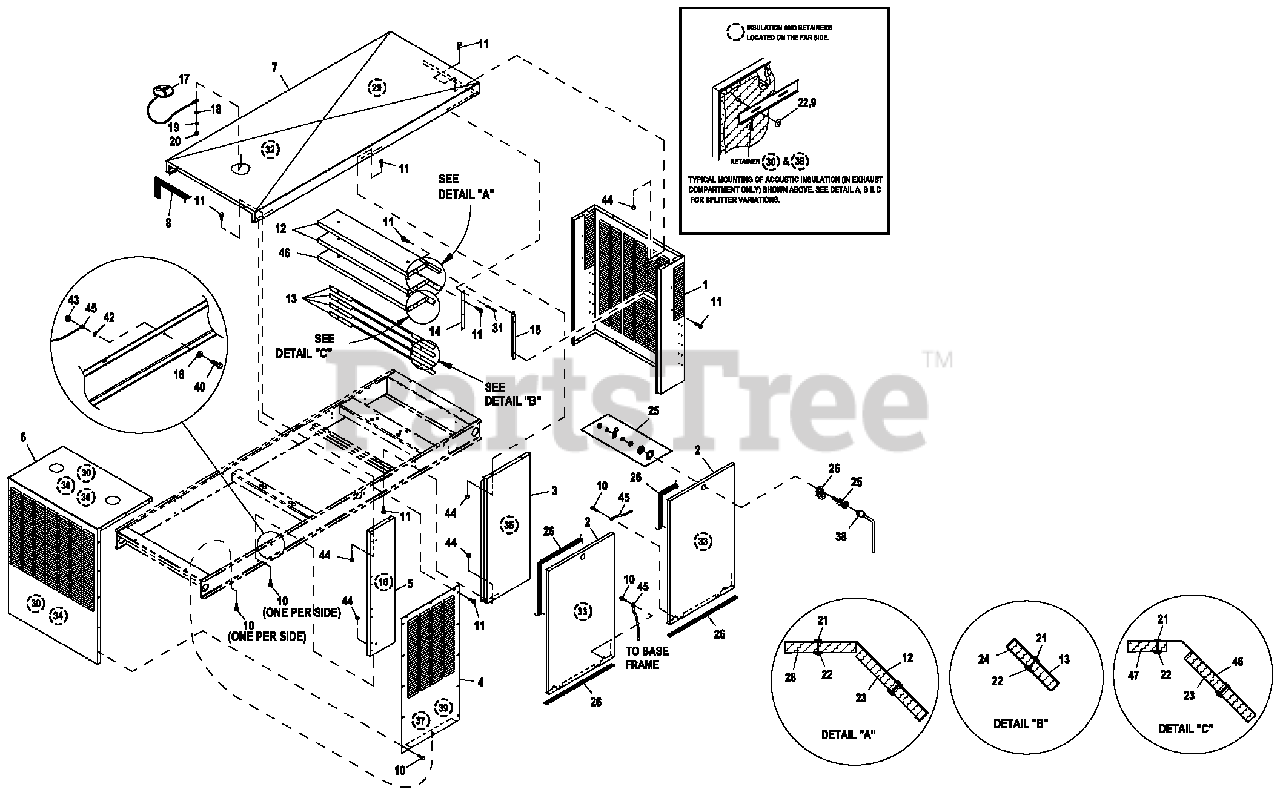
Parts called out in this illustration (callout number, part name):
1	REAR WRAP C5
2	DOOR C5
3	CENTER SUPPORT C5
4	DISCHARGE DUCT LH & RH SIDE C5
5	FRONT CORNERS C5
6	DUCT CENTER DISCHARGE RAW
7	ROOF C5ALUM
8	STRIP SEALANT 1/8X1 (44.5"LG)
9	WASHER SELF LOC KING DOME #8-32
10	SCREW TH-FRM M6 W/CAP SH KPRF W
11	SCREW THF M6-1 X 16 N WA Z/JS
12	SPLITTER
13	SPLITTER SHORT
14	STRINGER SPLITTER C3
15	SUPPORT SPLITTER C5 130 KW
16	INSUL CORNER POST
17	ASSY ACCESS COVER
18	WASHER FLAT 1/4-M6 ZINC
19	WASHER LOCK M6-1/4
20	NUT HEX 1/4-20 STEEL
21	INSULATION RETAINMENT HANGER
22	WASHER SELF LOC KING DOME #4-40
23	INSUL SPLITTER
24	INSUL SHORT LOUVER
25	VISE-ACTION LATCH SLOTTED CIR
26	GAS KET EXTRUDED TRIM (566" LG)
27	PULL TAB DOOR LOC K SS
28	INSUL SPLITTER SML
29	INSUL ROOF TOP REAR
30	RETAINER INSULATION (740)
31	RIVET POP.1875 X .450 SS
32	INSUL ROOF TOP FRT
33	INSUL DOOR
34	INSUL DISCHARGE DUCT
35	INSUL CENTER SUPPORT
36	INSUL DISCHARGE DUCT TOP
37	INSUL INNER DUCT SIDE
38	KEY VISE-ACTION LATCH SLOT CIR
39	RETAINER INSULATION (450)
40	SCREW HHC M6-1.0X20 G8.8
42	WASHER SHA KEPROOF INT 1/4
43	NUT HEX M 6X1.0 G8 YELCHR
44	NUT HEX LOC K M6-1.0 SS NY INS
45	ASSY WIRE 14AWG GRN/YEL
46	SPLITTER C5
47	INSUL SPLITTER SHRTMPS
